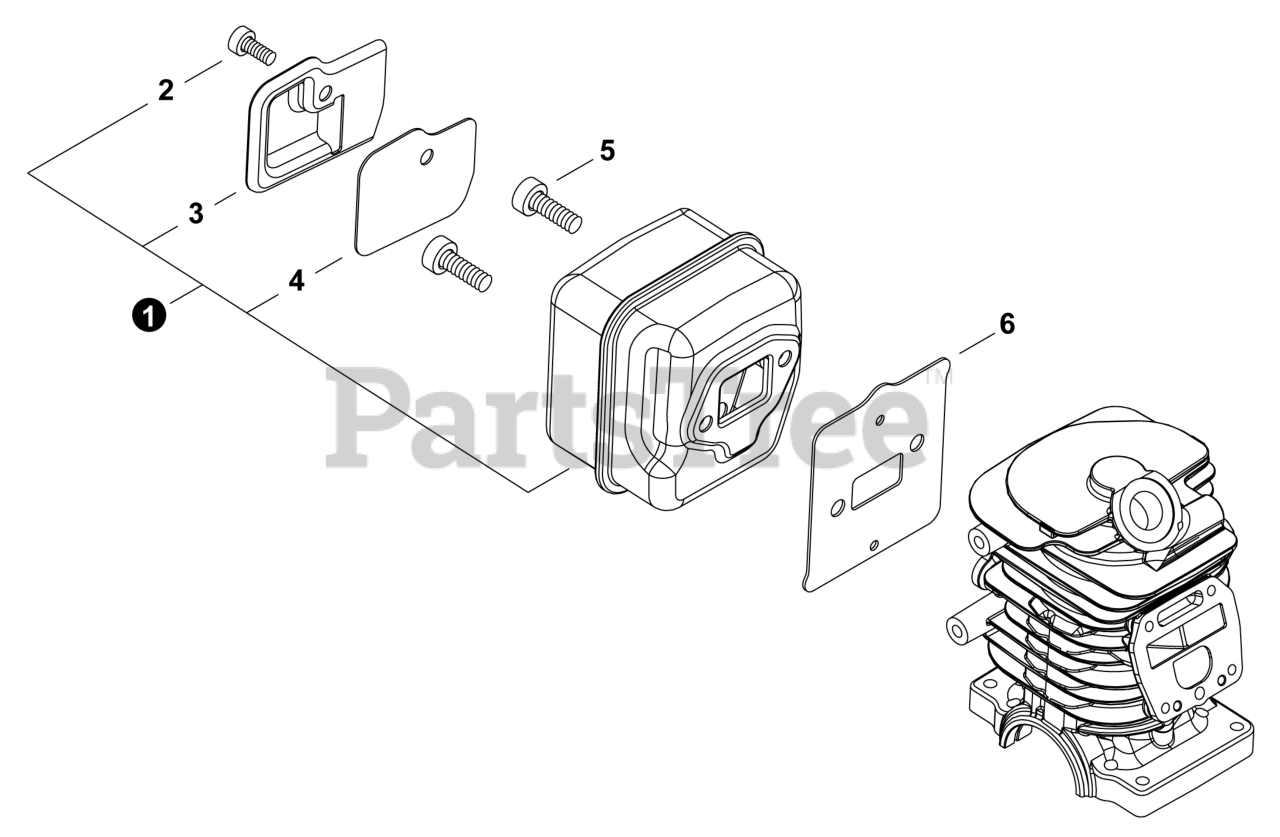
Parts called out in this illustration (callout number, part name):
1	MUFFLER ASSY
2	BOLT, TORX 5x8
3	GUIDE, EXHAUST
4	SCREEN, SPARK ARRESTER
5	BOLT, TORX 5x16
6	GASKET, EXHAUST
